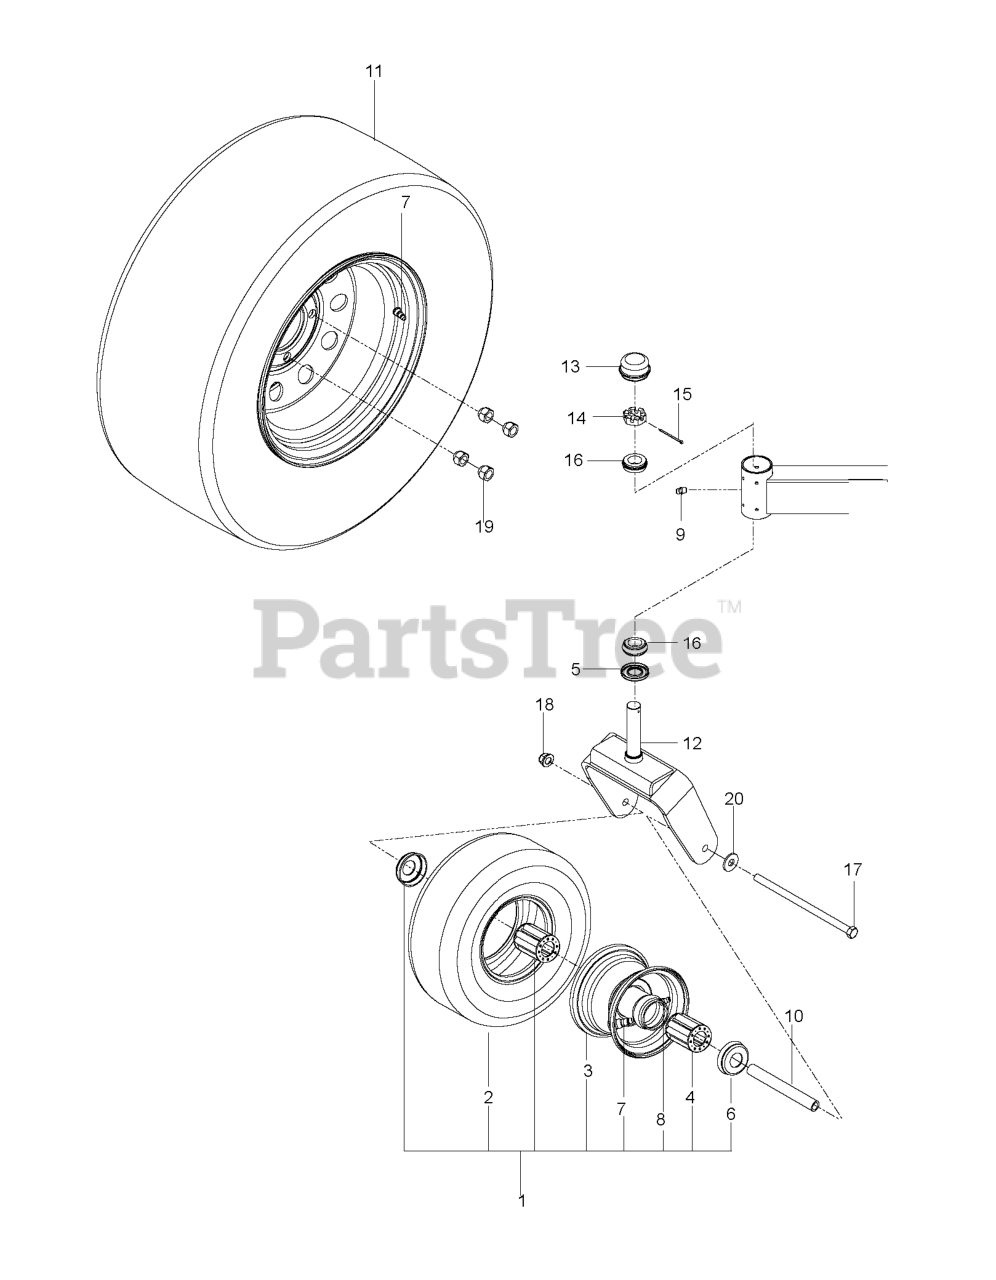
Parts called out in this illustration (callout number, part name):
1	TIRE.ASSEM.13X5-6.SMOOTH.SILVE
2	TIRE - FRONT
3	RIM
4	ROLLER BEARING
5	BEARING RETAINER
6	TAPERED ROLLER BRG
7	VALVE STEM TR-412
9	ZERK
10	SPACER, CASTER
11	TIRE/WHEEL.ASM.22X9.5-10
12	CASTER YOKE ORANGE
13	GREASE CAP
14	NUT 1"C HEX SLOTTED
15	COTTER PIN 1/8 X 2
17	SCREW 1/2C X 7 1/2 HEX CAP
18	NUT, 1/2-13 HEX FLG NYLOC ZD
19	LUG NUT 1/2F
20	WASH USS FLAT 1/2
